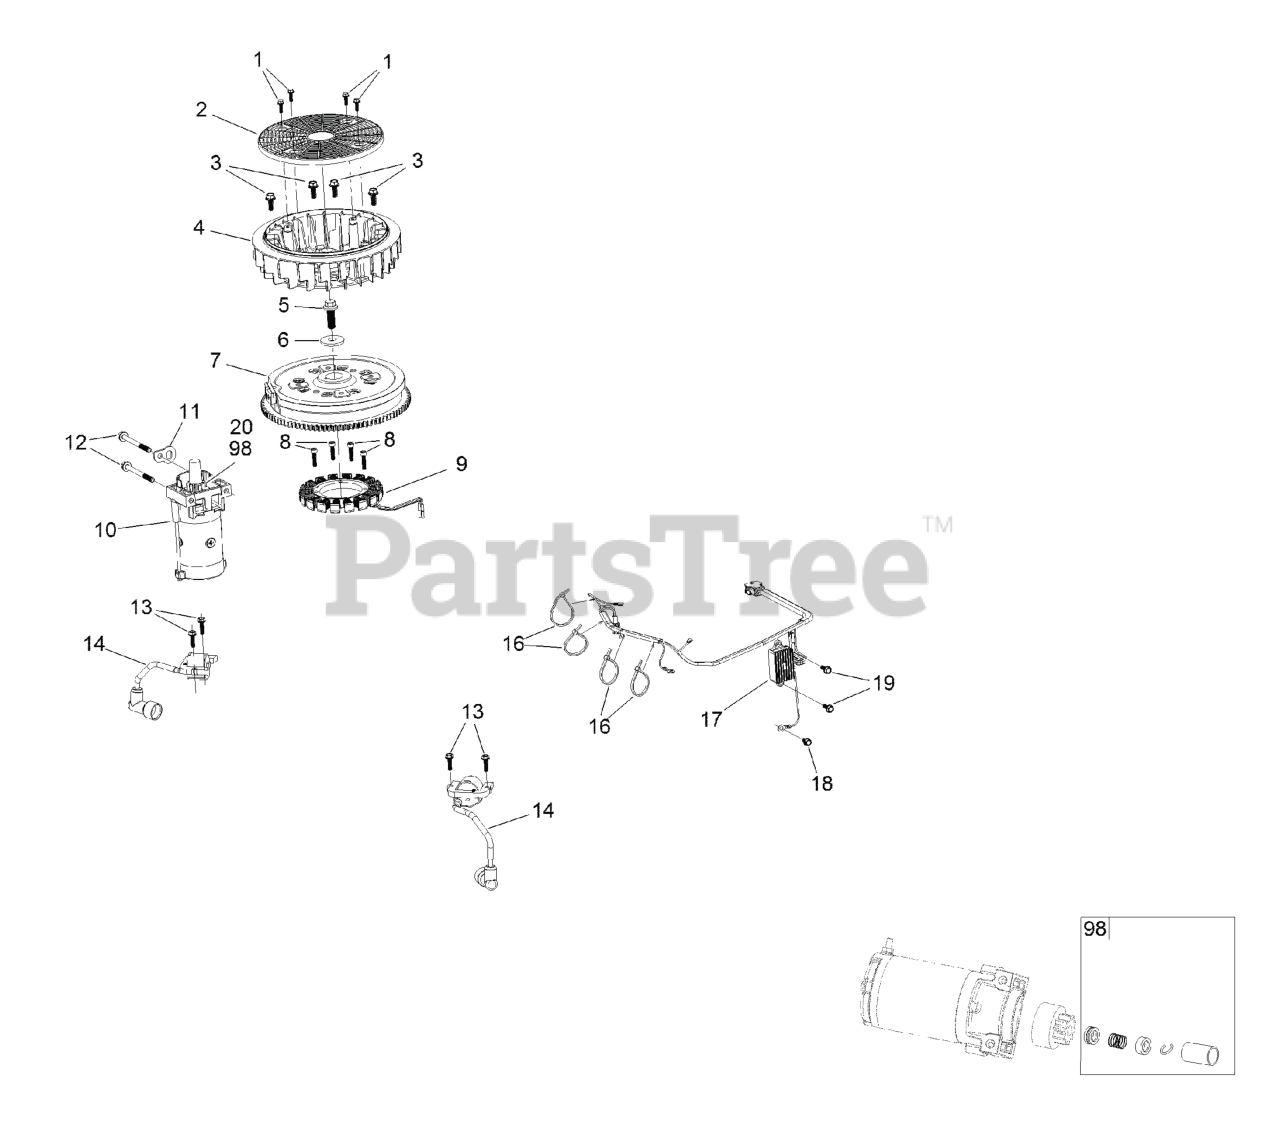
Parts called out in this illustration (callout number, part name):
1	SCREW-HWH
2	SCREEN-ROTATING
3	SCREW-HWH
4	FAN-COOLING
5	SCREW-HWH
6	WASHER-FLAT
7	FLYWHEEL
8	SCREW-HSH
9	ALTERNATOR
10	MOTOR-STARTER
11	BRACKET-LIFT
12	SCREW-HHF
13	BOLT-FLANGE
14	IGNITION COIL ASM
16	TIE-ZIP
17	REGULATOR-VOLTAGE, W/HARNESS
18	SCREW-HHF
19	SCREW-HHF
20	PINION-STARTER
98	STARTER REPAIR KIT
